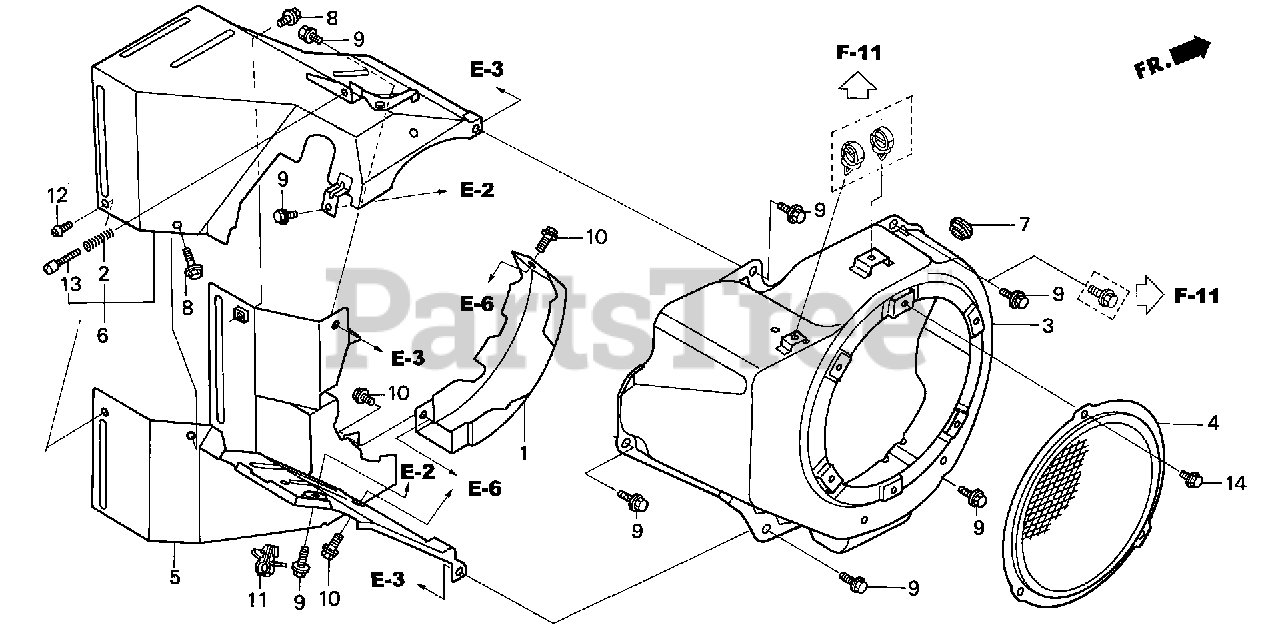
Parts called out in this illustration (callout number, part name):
1	SCROLL, GENERATOR FAN
2	SPRING, CONTROL ADJUSTING Use from Engine SN 2327377.
3	COVER, FAN
4	PROTECTOR, FAN COVER *R280* (POWER RED)
5	SHROUD (LOWER)
6	SHROUD ASSY. (UPPER)
7	GROMMET, DRAIN HOLE
8	BOLT, FLANGE (6X8)
9	BOLT, FLANGE (6X12) (CT200)
10	BOLT, FLANGE (5X10)
11	CLIP, WIRE HARNESS (6MM) (WHITE)
12	SCREW, PAN (5X8)
13	SCREW, PAN (5X32)
14	BOLT, FLANGE (6X10)
